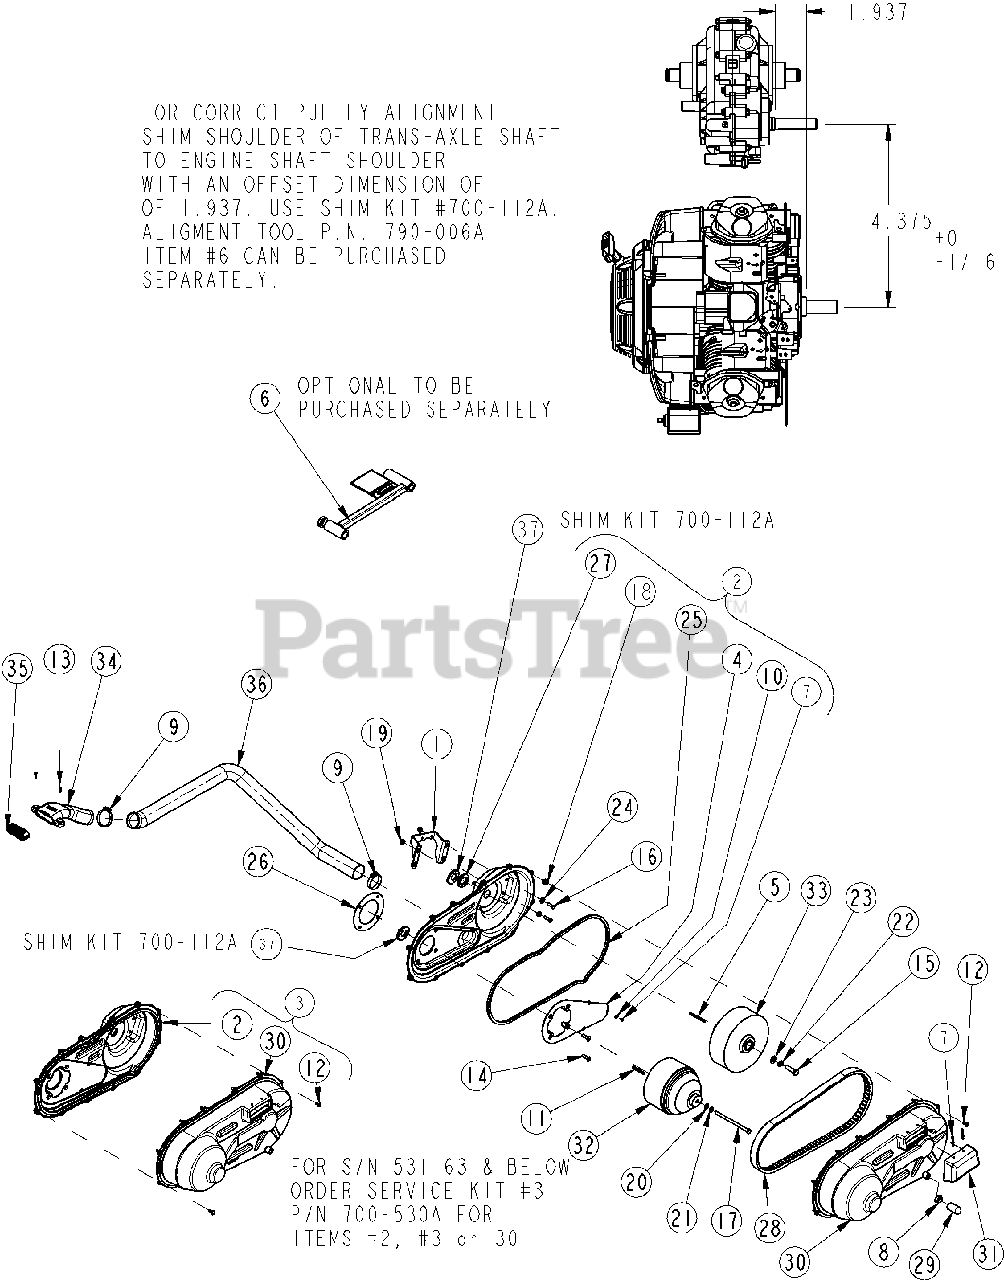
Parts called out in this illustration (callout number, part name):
1	BRACKET, CVT COVER TO TRANS.
2	ASSEMBLY, CVT INNER COVER
3	KIT, CVT SERVICE S/N 531163 & Below Redesigned
4	COVER, CVT INLET DUCT
5	KEY 3/16 X 3
6	TREKER ENGINE/TRANS ALIGN TOOL Optional W/ Manual
7	RIVET POP 3/16 .126-.250
8	SPRING CLAMP 1" OD HOSE
9	CLAMP WRM DRV#36SS (1.81-2.75)
10	RIVET POP WASHER 3/16
11	KEY .187 X .247 X 2.5 LG
12	TPHMS Y 1/4-20X3/4 YELLOW DIE
13	SCR SELF TAP #10 X 3/4
14	HSFHCS 5/16-24 X 1 1/4, BLK Apply Loctite
15	HHCS 1/2-20X2 GR5
16	BOLT, HEX 5/16-18 X 1 GR5 YWZC
17	HHCS 3/8-24X6 1/2 GR5 PLT
18	INSERT, 1/4-20 ARS4-420-280
19	NUT, TOP LOCK FLANGE .31-18
20	WASHER FLAT 3/8 SAE PLT
21	WASHER, LOCK 3/8
22	WASHER, LOCK 1/2
23	WASHER FLAT 1/2 SAE
24	WASHER FLAT 5/16 NEOPRENE PLT
25	SEAL, MAIN TRUCK CVT HOUSING
26	SEAL, CVT TO ENGINE
27	SEAL, CVT TO TRANSAXLE
28	BELT, CVT -LP3
29	CAP, DRAIN 7/8 OD PORT
30	ENCLOSURE, CVT OUTER
31	OUTLET DIVERTER, CVT
32	DRIVER, POWERBLOC - LP3
33	DRIVEN, CVTECH POWERBLOC-LP3
34	SNORKEL AIR INTAKE
35	FILTER, AIR INTAKE
36	HOSE, CVT AIR INTAKE
37	CVT SHIM KIT
